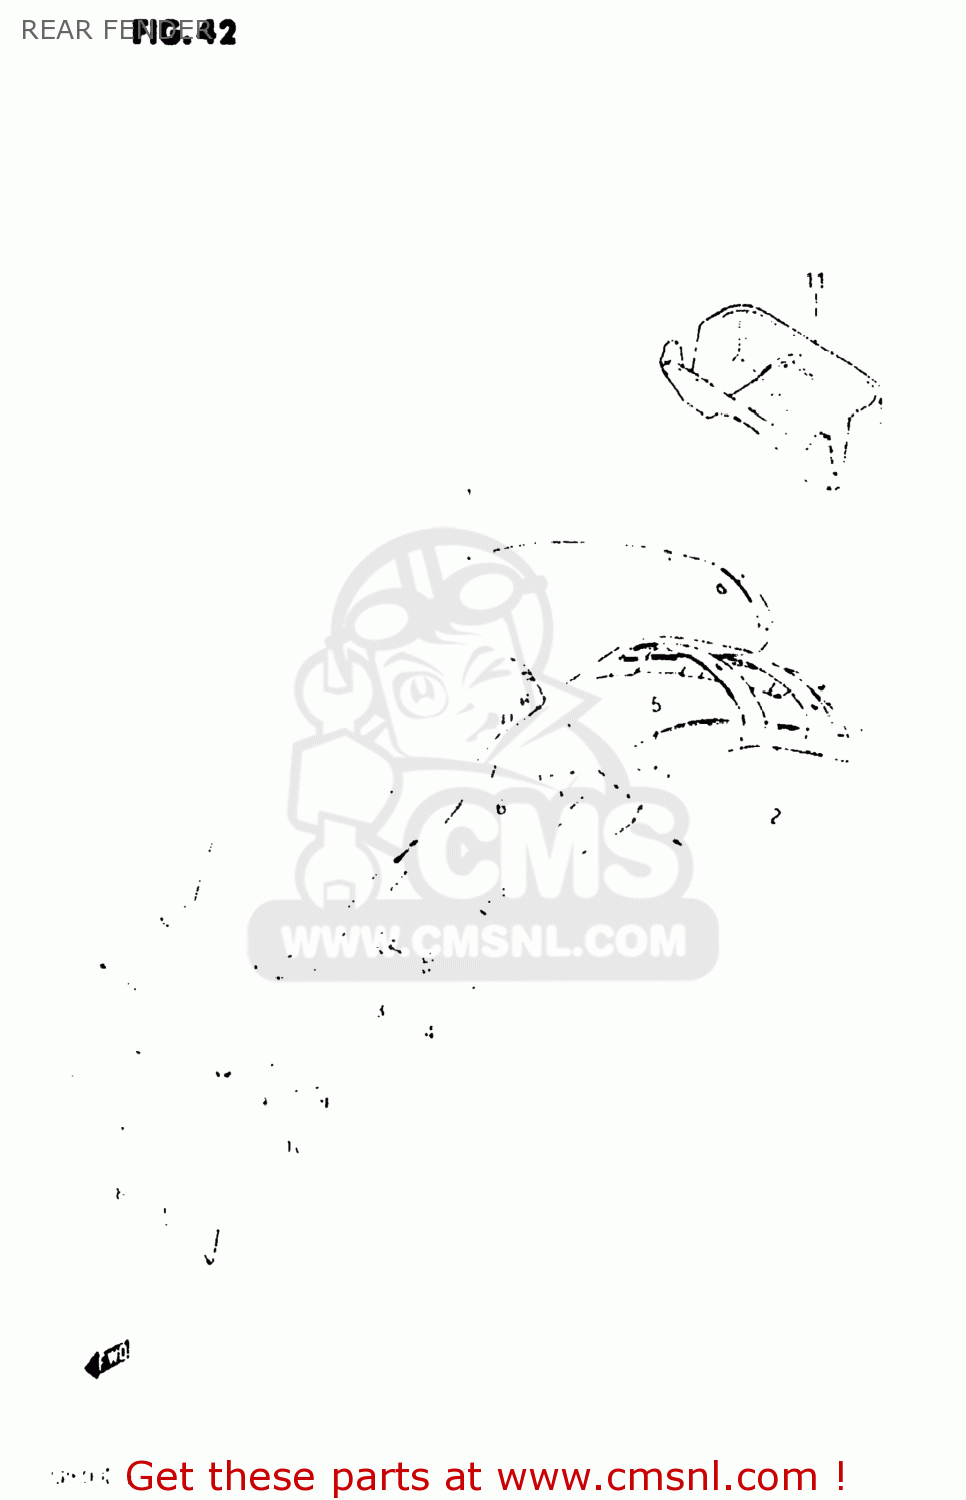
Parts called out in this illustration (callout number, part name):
1	FENDER,REAR
2	REINFORCEMENT,REAR FENDER
3	BOLT
4	LOCK WASHER
5	BOLT (8X30)
6	WASHER
7	NUT
8	MUD GUARD,REAR FENDER
9	MUD GUARD,REAR FENDER
10	CLAMP L:110
11	BAG ASSEMBLY,SEAT TAIL
